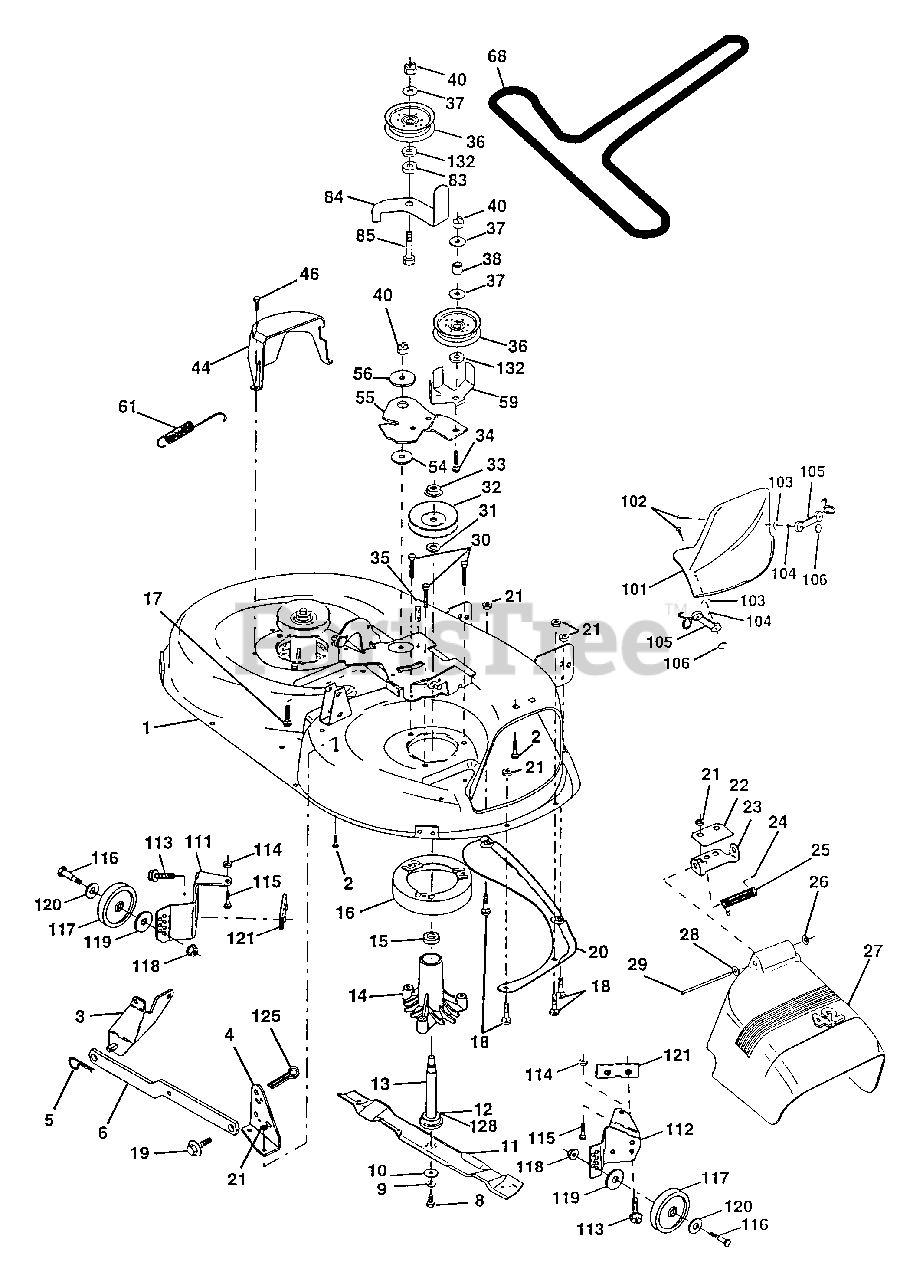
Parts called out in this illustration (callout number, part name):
1	Housing Asm Mower 42" 94 T-Path
2	Bolt Rdhd Sqnk 5/16-18 unc X 3/4
3	Bracket Asm., Sway Bar
4	Bracket Asm Deck 42" Sway Bar
5	Retainer Spring (AYP part number)
6	Arm, Suspension, Rear (Sway Bar) (AYP part number)
8	Bolt, Patched 3/8-24 x 1-1/4 Gr. 8
9	Washer, Lock Hvy., Unplated 3/8 (AYP part number)
10	Washer, Hard Blade, Mower Vented
11	Blade Mower Mulching 42"
12	Bearing, Ball, Mandrel #6204
13	Shaft Asm. w/Lower Bearing (AYP part number)
14	Housing, Mandrel
15	Bearing, Ball, Mandrel
16	Stripper, Mower Round (AYP part number)
17	Bolt Rdhd Sqnk 3/8-16 X 2-1/4
18	Bolt, Carriage 5/16-18 x 5/8
19	Bolt, Hex Head, Shoulder 5/16-18
20	Baffle, Vortex 42"
21	Nut, Crownlock 5/16-18 UNC
22	Stiffener, Bracket (AYP part number)
23	Bracket, Deflector (AYP part number)
24	Cap, Sleeve
25	Spring, Torsion, Deflector
26	Nut, Push
27	Shield, Deflector Mower 42" Blk
28	Washer 11/32 x 5/8 x 16 Ga.
29	Rod, Hinge
30	Screw, Hex Head, Thdroll (AYP part number)
31	Washer, Spacer Mower Vented (AYP part number)
32	Pulley, Mandrel 42" (AYP part number)
33	Nut, Flg. Top Lock Cntr. 9/16
34	Bolt Rdhd 3/8-16 unc X 2-3/4 Gr. 5
35	Fastner Christmas Tree
36	Pulley, Idler, Flat (AYP part number)
37	Washer 13/32 X 13/16 X 16 Ga.
38	Spacer Spring Stop Idler (AYP part number)
40	Nut Lock 3/8-16 Unc
44	Guard Mandrel LH Black
46	Screw, Thdroll. 1/4-20 x 5/8
54	Washer Hardened (AYP part number)
55	Arm Idler 42" mower LT/YT (AYP part number)
56	Spacer Retainer Pm Mower
59	Guard, Belt
61	Spring Ext. Elect
68	V-Belt Mower
83	Washer Sintered
84	Keeper Belt idler
85	Bolt Carriage 3/8-16 X 2-1/4 Gr. 5 (AYP part number)
101	Cover, Mulching
102	Screw (AYP part number)
103	Washer
104	Washer, Lock #10
105	Latch Asm. Bagger
106	Nut, Weld
111	Bracket Wheel Gauge Lh 42" Deck (AYP part number)
112	Bracket Gauge Wheel Rh 42" Deck (AYP part number)
113	Screw Thdrol 5/16-18 X 3/4 TYT
114	Nut Keps 5/16-18 UNC
115	Bolt Carriage 5/16Unc x 1/2 (AYP part number)
116	Bolt, Shoulder
117	Gauge Wheel
118	Nut, Centerlock 3/8-16 UNC
119	Washer 3/8 x 7/8 x 14 Ga.
120	Washer 17/32 X 15/16 X 12 Ga
121	Bracket
125	Cotter Pin
128	Washer Felt
132	Washer 13/32 X 1-3/8 X 3 Ga.
